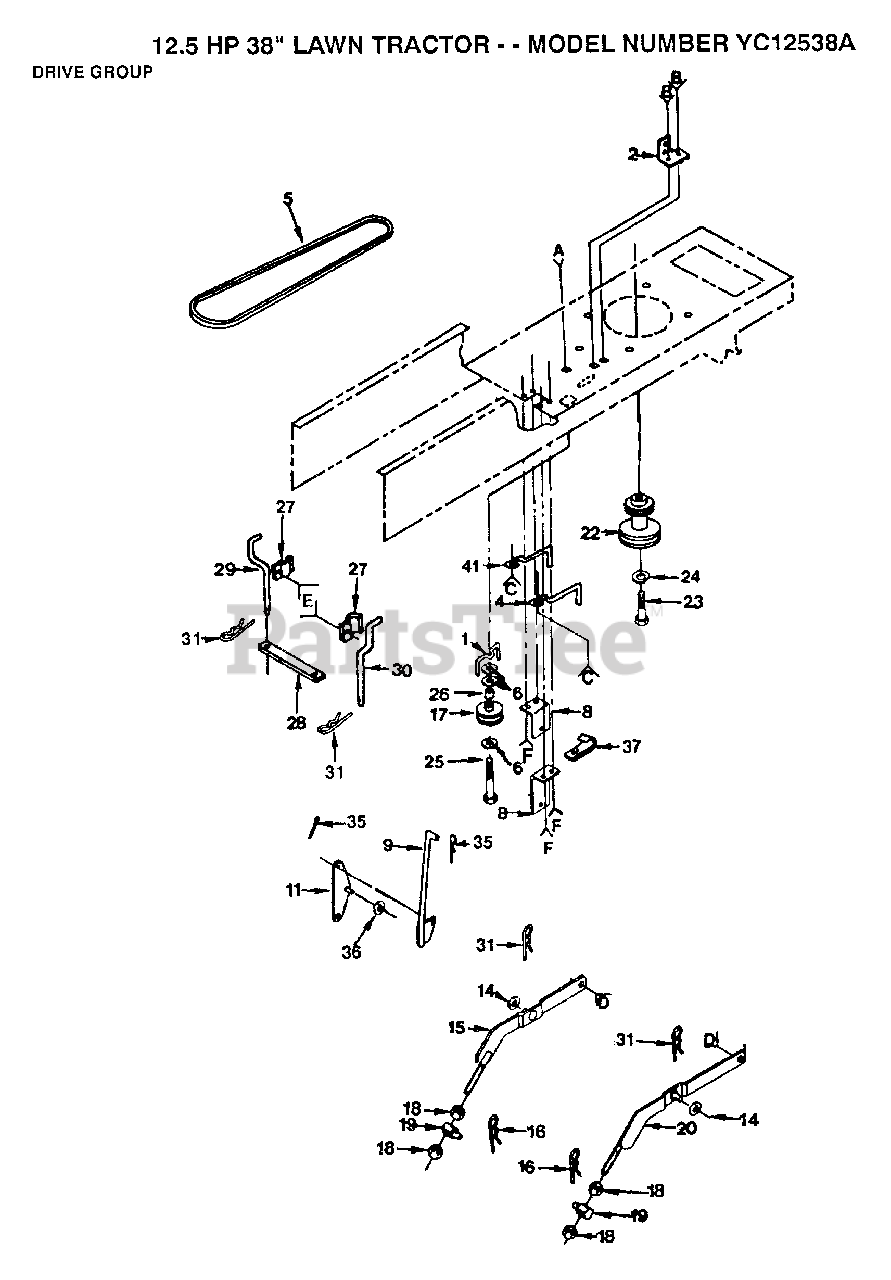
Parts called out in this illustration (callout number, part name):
1	BELT KEEPER LT
2	BRACKET LT
4	"KEEPER,BLT ENG LT"
5	BELT-V.90.0.GD.DR
6	WASHER
8	"BRKT,BELLCRAN T"
11	"T, BELLCRANK"
15	LH SUSP ARM ASM
16	SPRING H
17	PULLEY.IDLER.FLAT
18	NUT
20	RH SUSP ARM ASM
23	BOLT
24	LOCKWASHER
25	BOLT
26	SPACER T
27	CLAMP LT
28	STRAP LOCATOR
29	KEEPER BELT LH
30	KEEPER BELTRH
31	SPRING.RETAINER
35	COTTER PIN
36	WASHER
37	INSUL CLIP T
41	KEEPER BELT ENGLH
